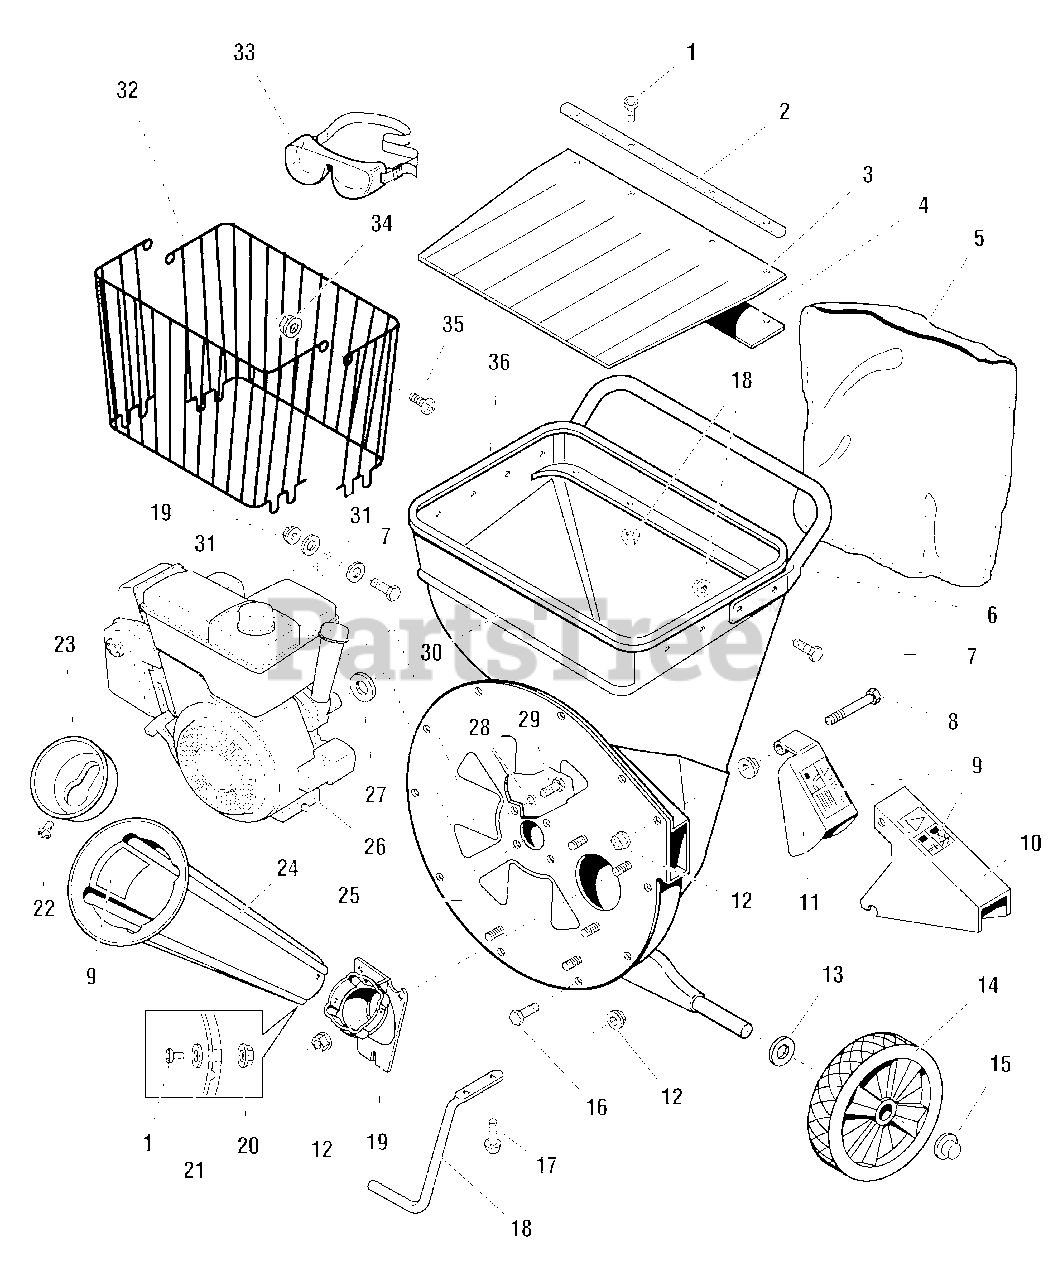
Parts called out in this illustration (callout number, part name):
1	SCREW, Hex, Button Hd., 1/4-20 x 3/4
2	RETAINING STRIP, Hopper Guard
3	GUARD, Hopper
4	SUPPORT, Hopper Guard
5	COLLECTION BAG, 24" x 34"
7	CAPSCREW, Hex, 1/4-20 x 1, Gr. 5
8	CAPSCREW, Hex, 5/16-18 x 3-1/4, Gr.5
9	DECAL, Danger, Rotating Cutting Blades, Warning, Debris
9	DECAL, Caution, Rotating Cuttinb Blades, Warning, Debris
10	DEFLECTOR, Fixed
11	DECAL, Caution, Do Not Operate Without Bag Attached
12	NUT, Whiz, 5/16-18
13	WASHER, Plain, 17/32Plain, 17/32 x 1-1/4 x 5/64
14	WHEEL & TIRE ASSEMBLY, 1-3/4 x 12
14	WHEEL & TIRE ASSEMBLY, 2-1/4 x 12
15	PUSH NUT, 1/2
16	CAPSCREW, Hex, 5/16-18 x 5/8
17	SCREW, Taptite, 3/8 16 x 1-1/4
19	CASTING, Chipper Cone, 3"
20	NUT, Flange, 2-Way Lock, 1/4-20
21	WASHER, Plain, 17/64 x 5/18 x 31/64
22	SCREW, Round Head, Phillips, 1/4-20 x 1/2
23	INSERT, Cone (CE model only)
24	CONE, Chipper, Red
25	ENGINE PLATE ASSEMBLY
26	ENGINE, 5HP, Briggs & Stratton
26	ENGINE, 8HP, Briggs & Stratton
28	LOCKWASHER, 5/16
29	CAPSCREW, Hex Head, 5/16-24 x 3/4
30	DECAL, 5/14, Simplicity
30	DECAL, 8/14, Simplicity Pro
31	WASHER, Plain, 1/4 x 1-1/4 x 5/64
32	HOPPER HALF, Upper
33	SAFETY GOGGLES
34	NUT, Flange Whiz Lock, 5/16-18
35	SCREW, Truss Head, 5/16-18 x 3/4
36	HOPPER, Red
37	DECAL, Danger, Rotating Cutting Blades, Warning, Debris
37	DECAL, Caution, Rotating Cuttinb Blades, Warning, Debris
